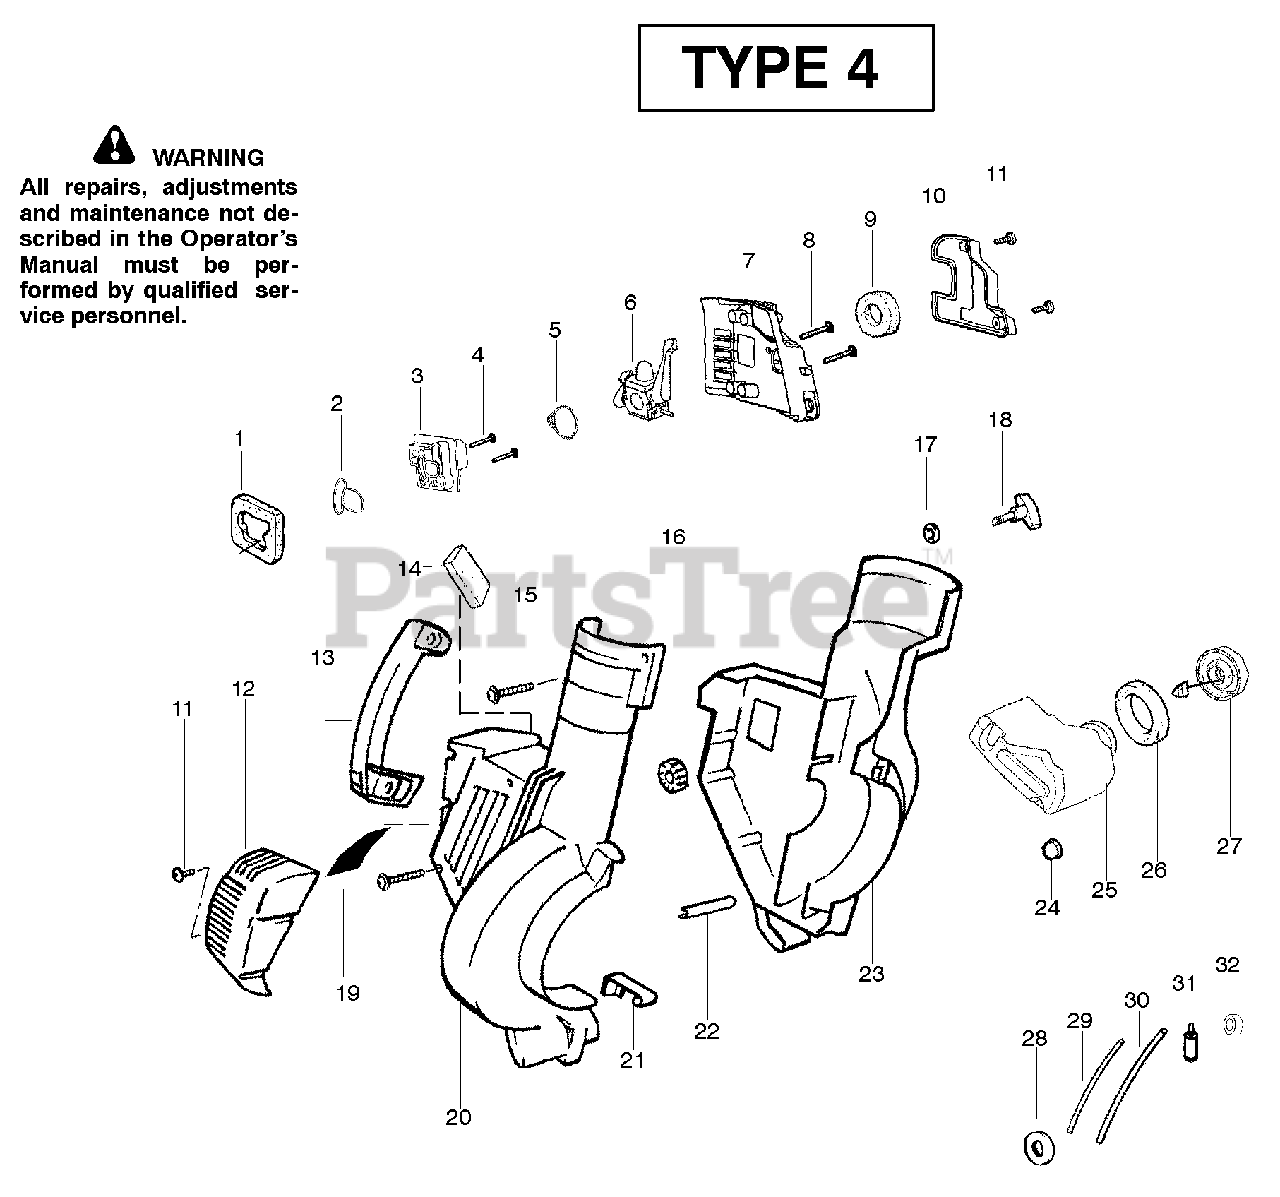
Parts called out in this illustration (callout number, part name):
1	Air Dam (kit)
2	Gasket-Adapter (kit)
3	Carburetor Adaptor
5	Gasket-Carburetor (kit)
6	Kit-Carb Ass'y. (C1Q-W11)
6	Kit-Carb Ass'y. (Wt-606)
8	Screw-Carb.
9	Filter-Air
10	Cover-Air Filter
12	Guard-Muffler
14	Foam - 71.12mm (kit)
16	Isolator
18	Knob-Tube Clamp
19	Reflector-Heat (kit)
20	Assy-Housing-Right
21	Spring-Cover Latch
22	Guide-Starter Rope
23	Housing-Left
24	Isolator-Crankcase
25	Assy-Fuel Tank
26	Gasket-Fuel Tank
27	Fuel Cap w/Retainer
28	Grommet-Shroud
29	Kit-Line Carb/Purge
30	Kit-Line Tank/Purge
31	Assy-Fuel Pick-up
32	Grommet-Fuel line (kit)
